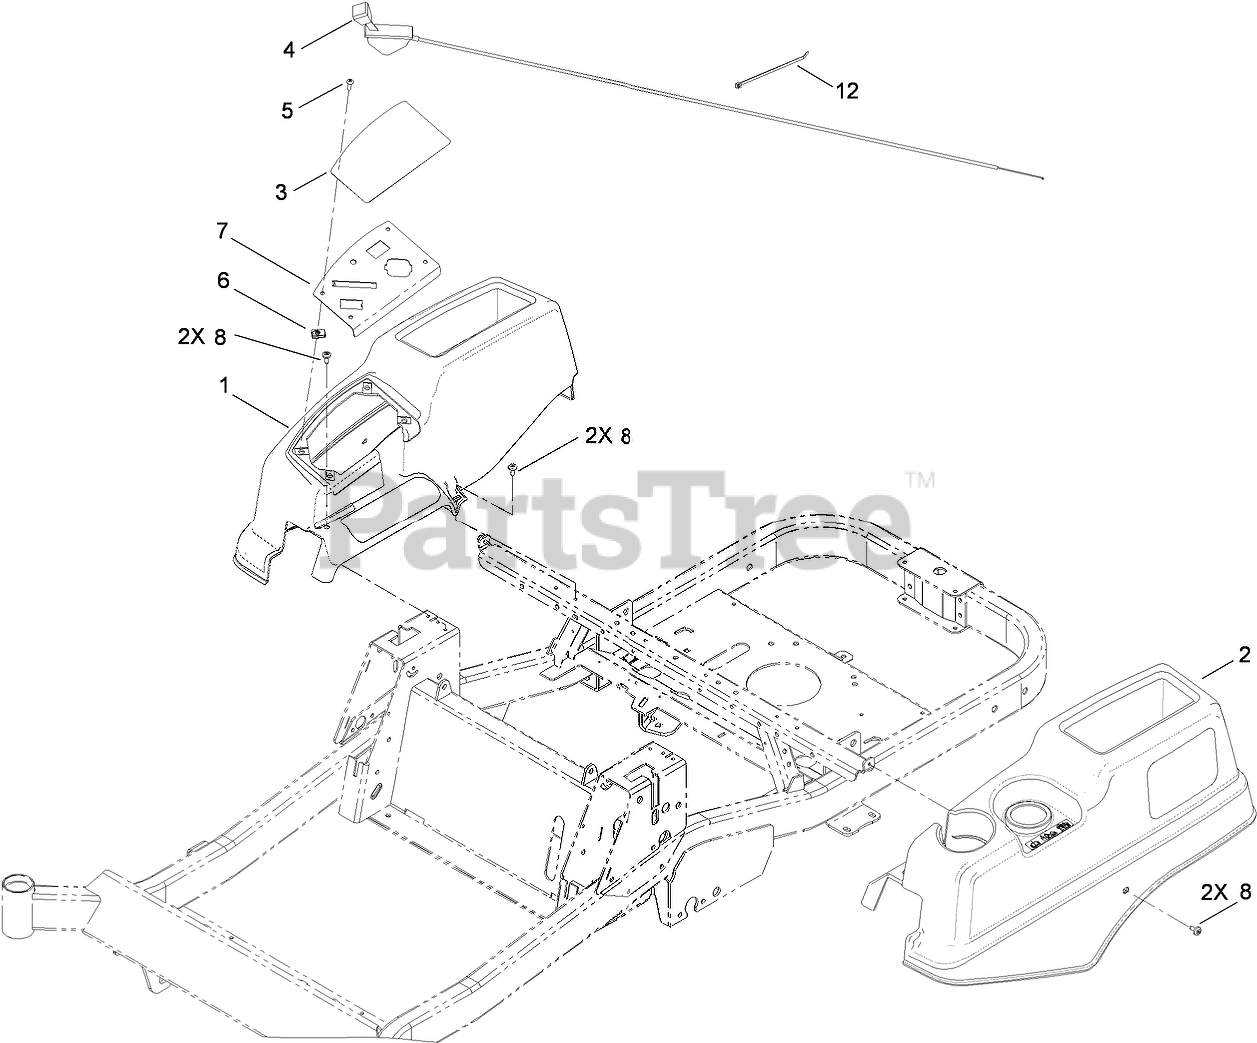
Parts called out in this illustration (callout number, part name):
1	POD-RH
2	POD-LH
3	DECAL-PANEL, CONTROL
4	CABLE-THROTTLE
5	SCREW-PRH
7	PANEL-CONTROL
8	SCREW-SHOULDER
12	TIE-CABLE
